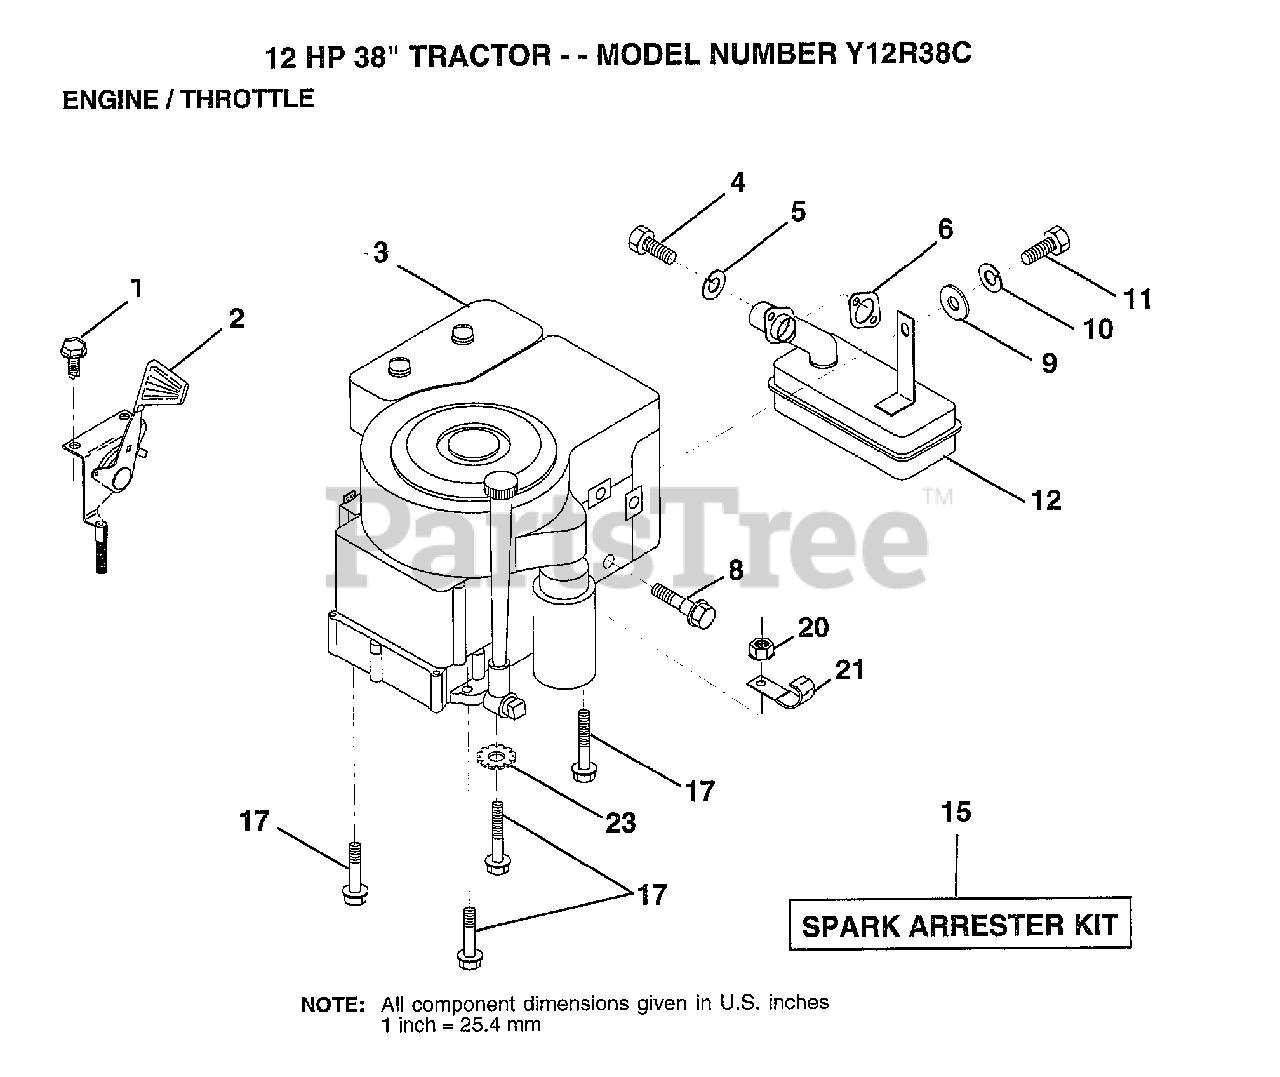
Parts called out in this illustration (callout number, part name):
1	SCREW.1/4-20X1/2
2	"CONTROL,THROTTLE"
4	SCREW
5	LOCKWASHER
8	BOLT T
10	LOCKWASHER
12	MUFFLER
17	SCREW LT
20	NUT
21	CLIP T
23	LOCKWASHER
